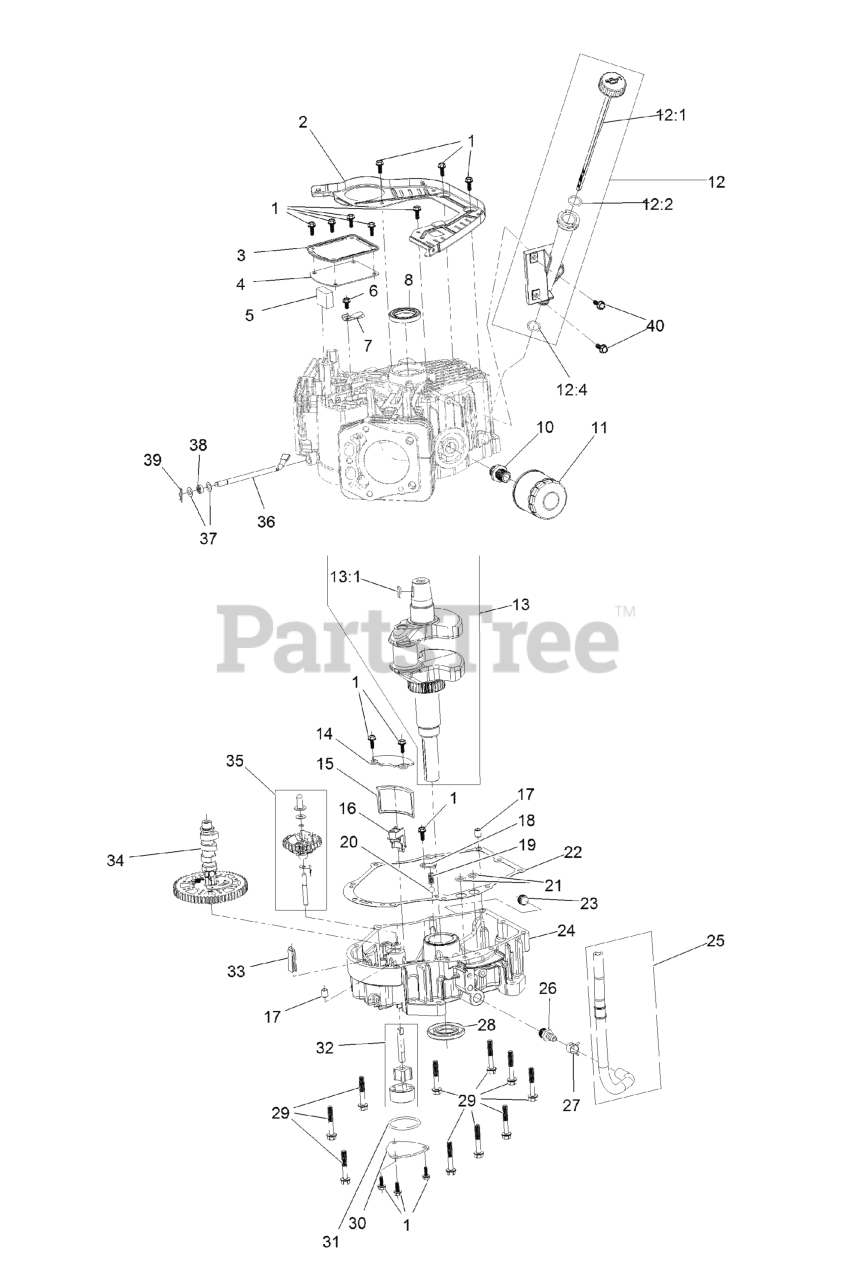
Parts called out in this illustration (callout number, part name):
1	SCREW-HHF
3	COVER-BREATHER
4	GASKET-BREATHER
5	FILTER-BREATHER
6	SCREW-HHF
7	VALVE-BREATHER
8	SEAL-OIL
10	ADAPTOR-FILTER, OIL
11	FILTER-OIL
12	OIL TUBE ASM
12:1	DIPSTICK
13	CRANKSHAFT
13:1	KEY-WOODRUFF
14	COVER-SCREEN, OIL
15	SCREEN-OIL
16	RETAINER-SCREEN
17	PIN-DOWEL
18	PLATE-RETAINER
20	VALVE-BALL
22	GASKET-COVER, CRANKCASE
23	PLUG-DRAIN
24	COVER-CRANKCASE
25	OIL DRAIN HOSE ASM
26	FITTING-HOSE
27	CLAMP-HOSE
29	SCREW-HHF
30	COVER-OIL PUMP
32	OIL PUMP ASM
33	DEFLECTOR-OIL, RUBBER
34	CAMSHAFT
35	GOVERNOR ASM
36	SHAFT-GOVERNOR
37	WASHER-PLAIN
38	SEAL-OIL
39	PIN-HAIR
40	SCREW-HHF
